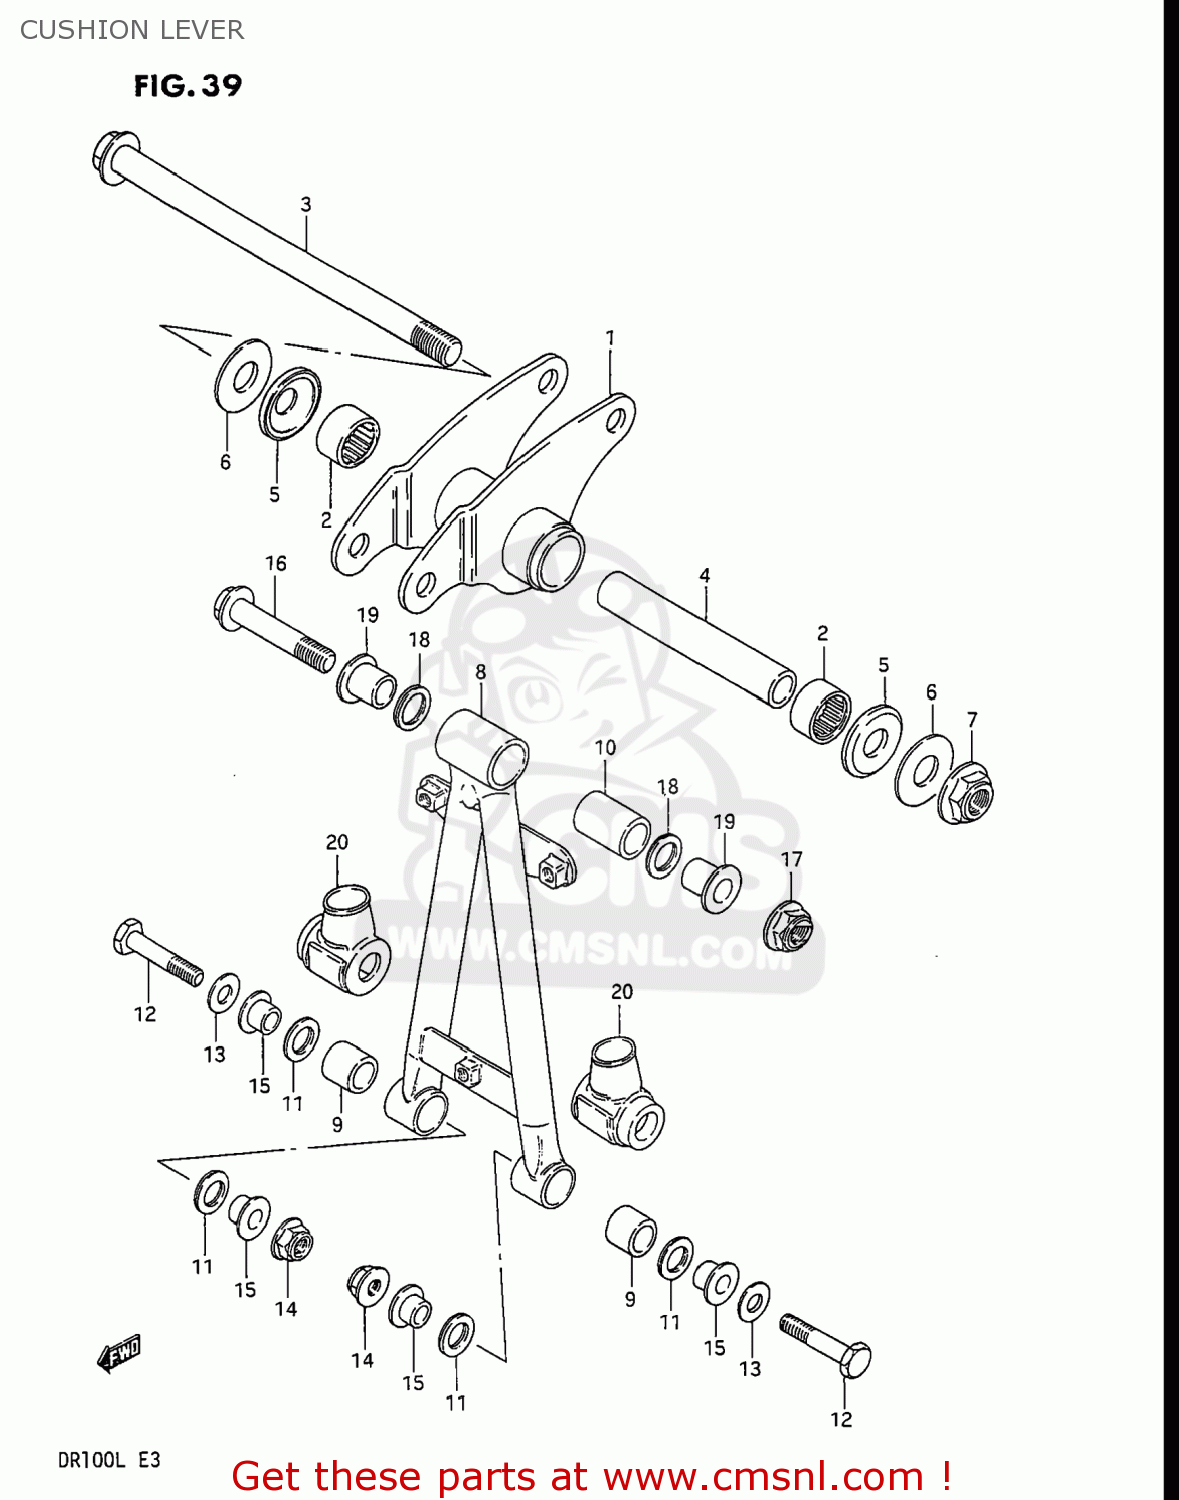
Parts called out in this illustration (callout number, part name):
1	LEVER SET,REAR CUSHION
2	BEARING(17X25X20)
3	SHAFT,REAR CUSHION LEVER
4	SPACER,REAR CUSHION LEVER
5	DUST SEAL,REAR CUSHION,LEFT
6	WASHER
7	NUT 12MM
8	ROD SET,REAR CUSHION LEVER
9	BUSHING
10	BUSH,UPPER
11	DUST SEAL,RR CUSHION LOD LWR
12	BOLT,REAR CUSHION ROD
13	WASHER
14	NUT
15	SPACER,RR CUSHION ROD LWR
16	BOLT(10X65)
17	NUT
18	DUST SEAL,LEVER CUSHION UNIT
19	SPACER,RR CUSHION ROD UPR
20	BOOT,REAR CUSHION ROD,LOWER
